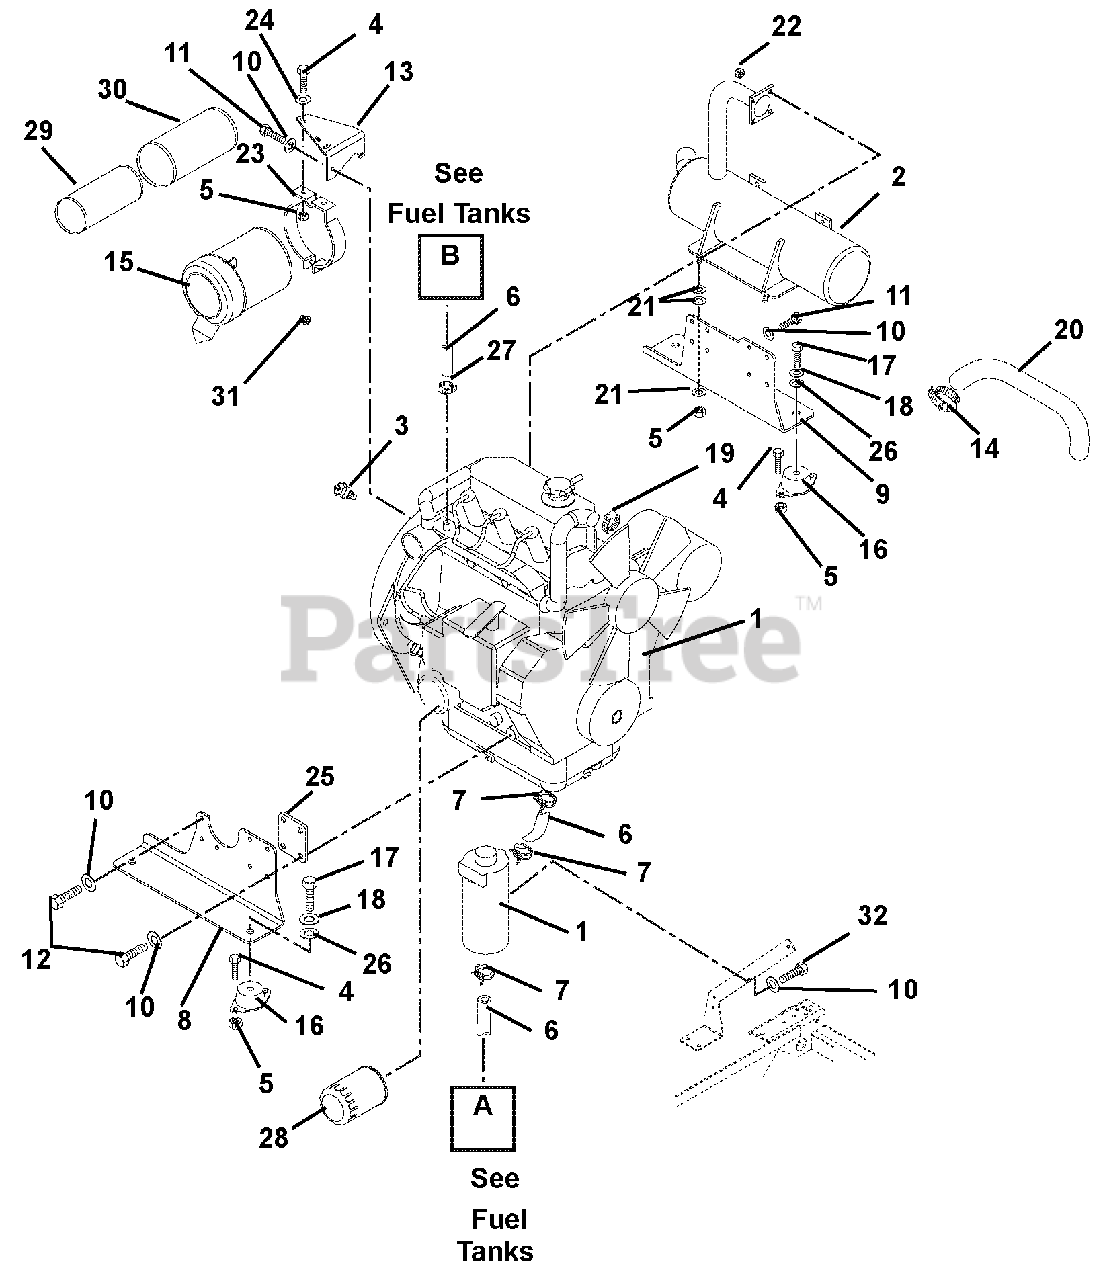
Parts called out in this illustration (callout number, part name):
1	ENGINE, 27HP DIESEL (DAIHATSU)
2	MUFFLER
3	SENDER, TEMPERATURE
4	@BLT-HEX .31-18X.75 GR5 YWZC
5	@NUT-LK-TOP-FLG .31-18 YWZC
6	HOSE,5/16 ID
7	CLAMP, HOSE WIRE .520/.550
8	MOUNT, ENGINE RH (DIESEL)
9	MOUNT, ENGINE LH (DIESEL)
10	@WSHR-LK .31X.078 REG YWZC
11	@BLT-HEX M8-1.25X20 YWZC
12	BLT, HEX M8-1.25X25 GR8.8YWZC
13	BRKT, AIR CLEANER - BLACK
14	CLAMP, HOSE #32 (1.56/2.50)
15	AIR CLEANER ASSEMBLY
16	MOUNT, ENGINE, VIBRATION ISO
17	BLT-HEX .50-20X1.00 GR5 YWZC
18	@WSHR-LK .50X.125 REG YWZC
19	CLAMP-HOSE 1.50X.81X1.42
20	HOSE, AIR CLEANER
21	@WSHR-FL-STL.38X.875X.083 YWZC
22	NUT-LK-TOP M8-1.25 YWZC
23	BRACKET, AIR CLEANER MOUNT
24	@WSHR-FL-STL.38X.875X.083 YWZC
25	SPACER, ENGINE MTG (DIESEL)
26	@WSHR-FL-STL.531X1.06X.095YWZC
27	CLAMP, HOSE, IDEAL 6202 SIZE 4
28	FILTER, OIL
29	ELEMENT, INNER SAFETY
30	ELEMENT, OUTER PRIMARY
31	PLUG, PIPE .125-27 SLHD YWZC
32	@BLT-HEX M6-1X16 YWZC
